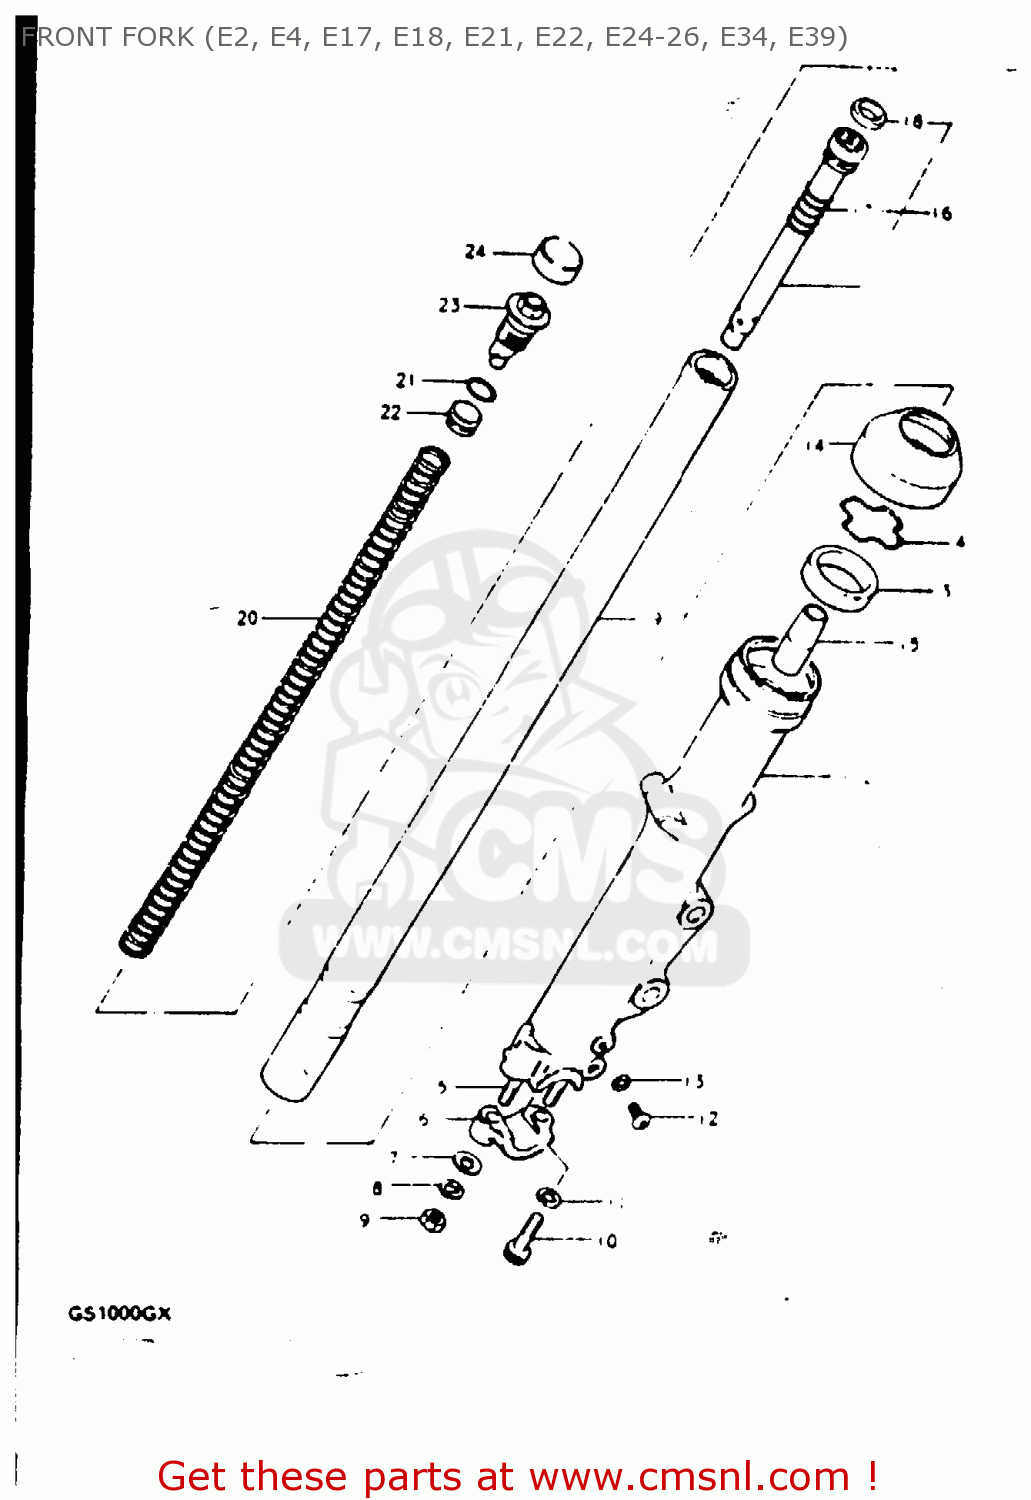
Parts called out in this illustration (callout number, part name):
1	TUBE,FORK,OUTER,RIGHT
2	TUBE,FORK,LEFT,OUTER
3	OIL SEAL,FRONT FORK
4	RING,STOPPER
5	STUD BOLT
6	HOLDER,AXLE
7	WASHER
8	LOCK WASHER
9	NUT (8MM)
10	BOLT,FORK CYLINDER(10X25)
11	GASKET (NAS)
12	SCREW
13	GASKET,DRAIN,PLUG (NAS)
14	SEAL,DUST
15	PIECE,OIL LOCK
16	CYLINDER
17	SPRING,REBOUND
18	RING,PISTON
19	INNER TUBE
20	SPRING,FRONT FORK
21	O-RING
22	PISTON,FREE
23	CAP
24	CAP
